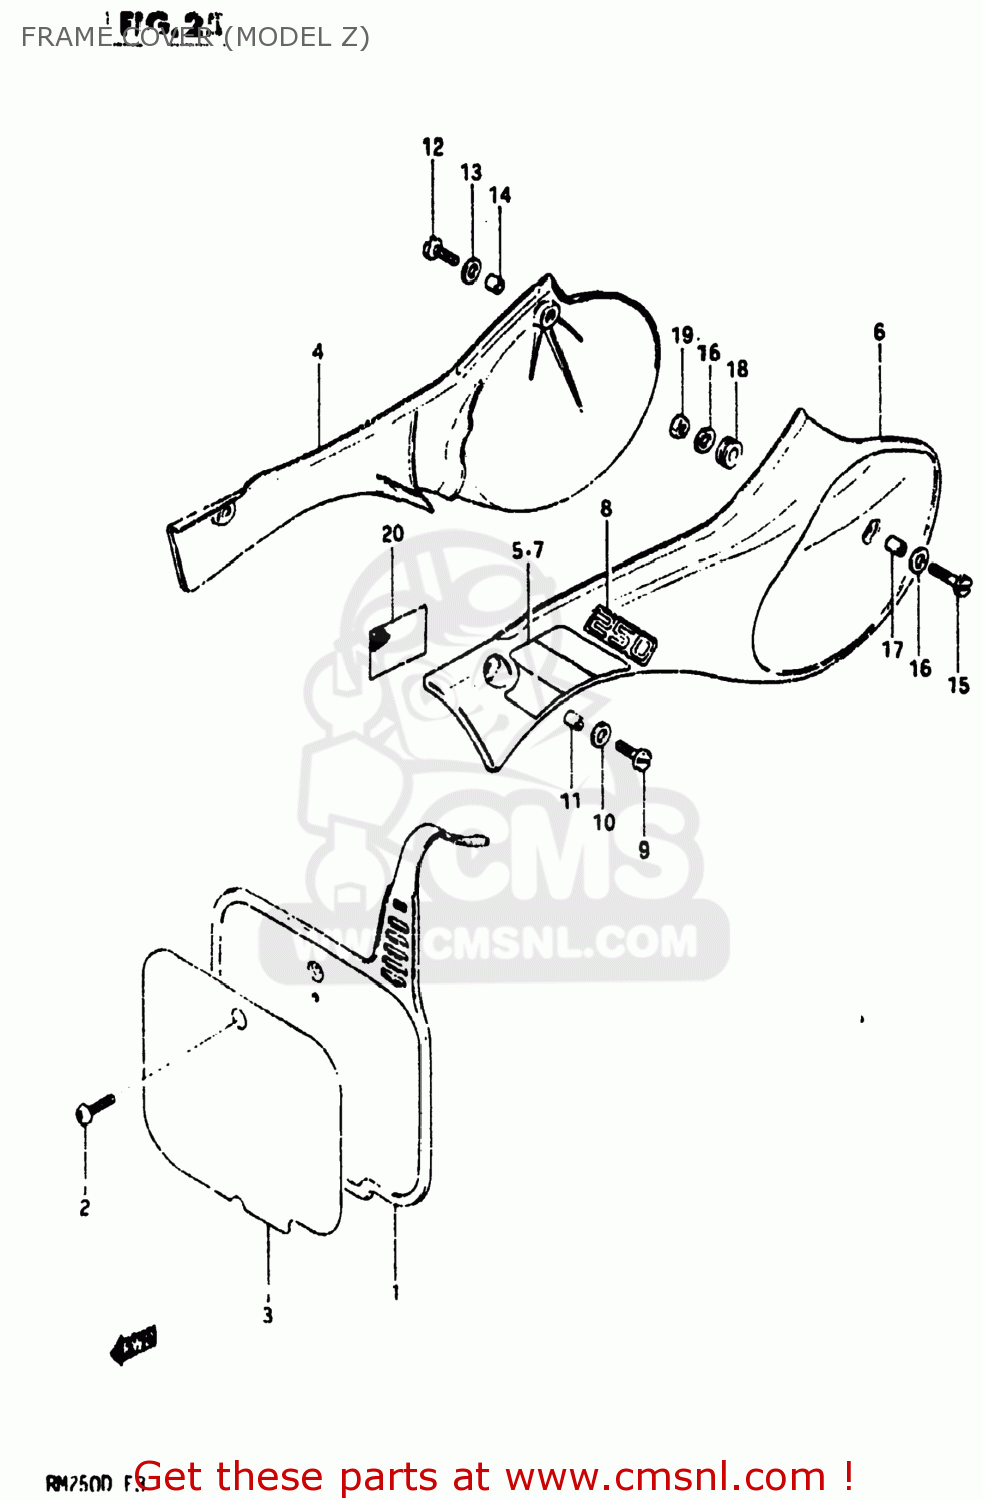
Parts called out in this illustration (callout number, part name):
1	PLATE,NUMBER,FRONT
2	SCREW
3	EMBLEM,FRONT NUMBER PLATE
4	COVER,FRAME,RIGHT
5	TAPE,FRAME COVER,RIGHT
6	COVER,FRAME,LEFT
7	TAPE,FRAME COVER,LEFT
8	EMBLEM (250)
9	SCREW(6X25)
10	WASHER FRAME COVER
11	SPACER,FRAME COVER,FRONT
12	SCREW
13	WASHER FRAME COVER
14	SPACER FRAME COV RR
15	SCREW
16	WASHER FRAME COVER
17	SPACER,FRAME COVER,FRONT
18	CUSHION
19	NUT 6MM
20	HEAT SHIELD,FRAME COVER
